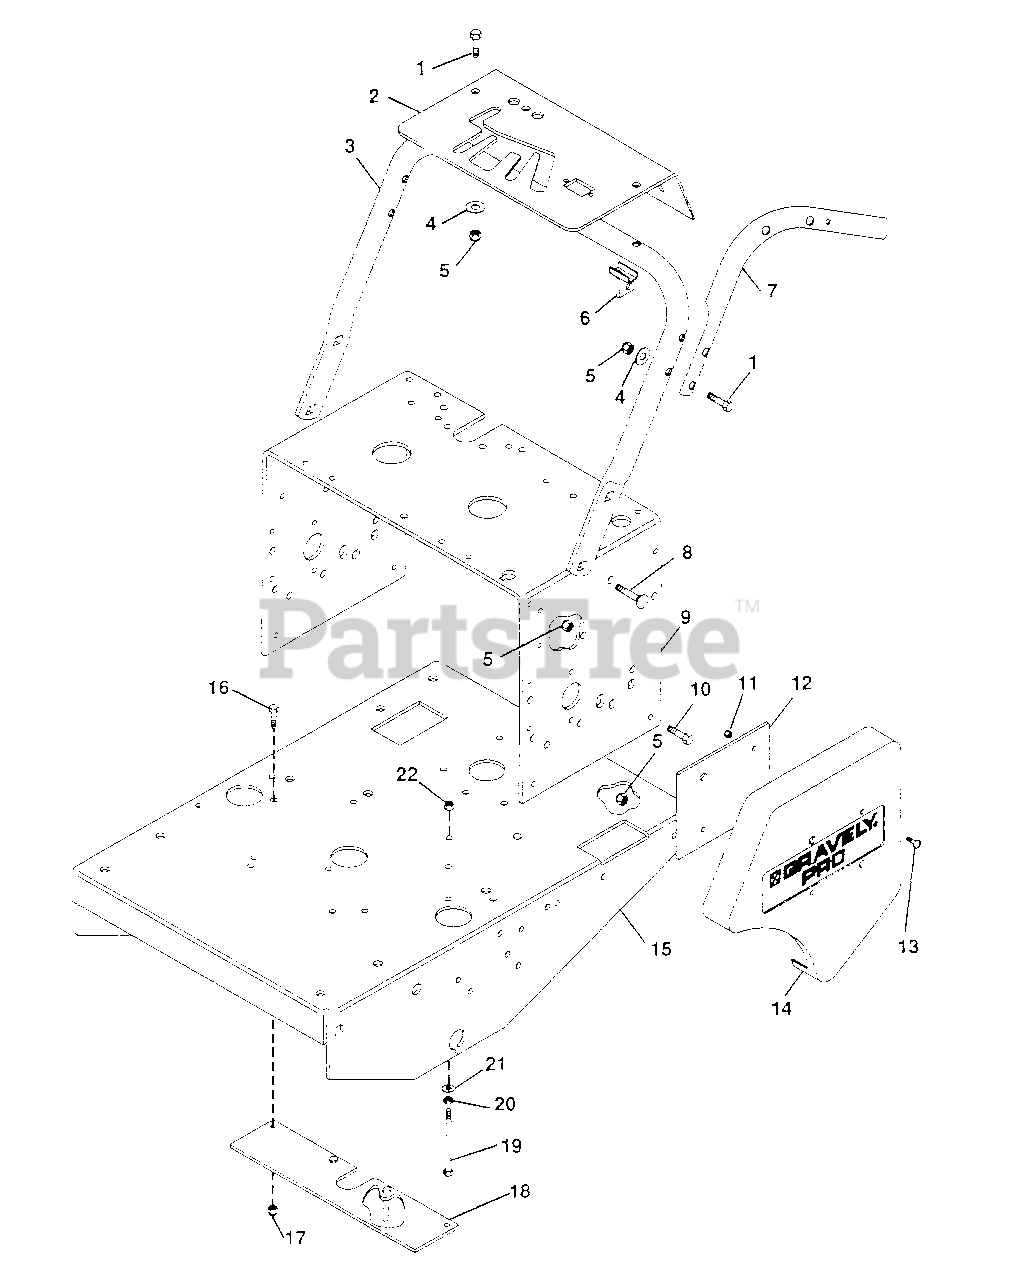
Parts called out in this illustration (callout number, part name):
1	BOLT, HEX 3/8-16X2.00
2	PANEL, SILK SCREEN
3	TUBE, HANDLEBAR MOUNTING
4	WASHER, FLAT .406X.812X.065
5	NUT, LOCK 3/8-16
6	WELDMENT, PTO LEVER MOUNTING
7	HANDLEBAR, L.H.
7	HANDLEBAR, R.H.
8	BOLT, 3/8-16X1.00 RD HD SQ NK
9	SUPPORT, HANDLEBAR
10	BOLT, HEX 3/8-16X1.00
11	NUT, LOCK 1/4-20
12	BRACKET, BELT GUARD L.H.
13	SCREW, MACH. 1/4-20 PHD
14	GUARD, BELT R.H.
15	FRAME, PRO
16	BOLT, EX 5/16-18X.75
17	NUT, LOCK 5/16-18
18	WELDMENT, BELT GUARD
19	BOLT, HEX 3/8-16X4.00
20	NUT, HEX 3/8-16
21	WASHER, FLAT .406X.812X.065
22	NUT, LOCK 3/8-16
